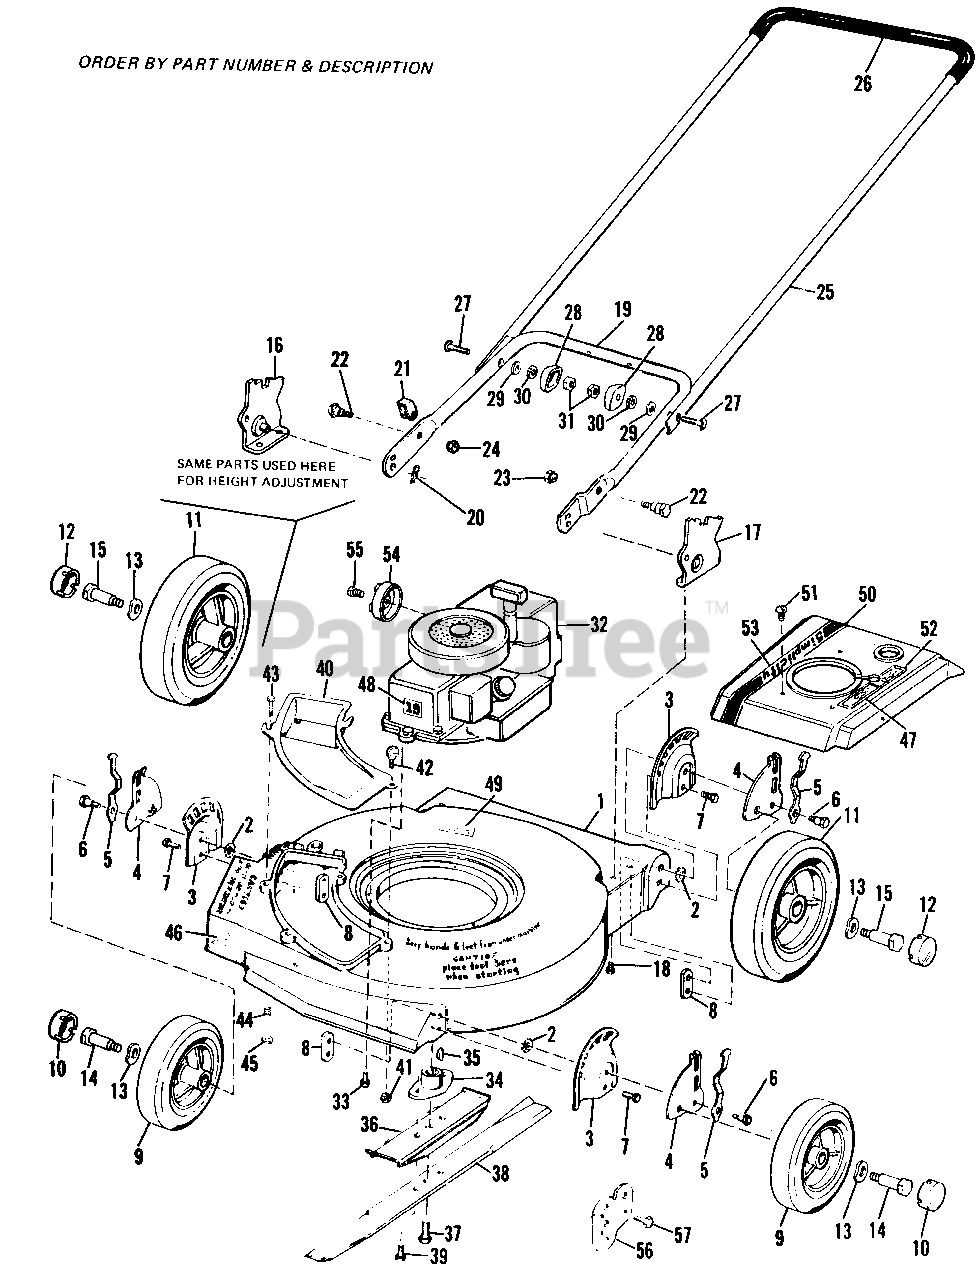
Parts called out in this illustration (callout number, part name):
1	HOUSING, 19"
2	LOCKWASHER, Shake Proof, 3/8" Ext. Type
3	PLATE, Adjusting
4	ADJUSTER, Height, Front & Rear
5	SPRING, Height Adj.
6	BOLT, Shoulder, Hex Hd.
7	CAPSCREW, Hex, 3/8-16 x 5/8
8	NUT, Pilot Twin
9	WHEEL & TIRE ASSY, 6" (Front)
10	CAP, Hub, 6"
11	WHEEL & TIRE ASSY, 8" (Rear)
12	CAP, Hub, 8"
13	WASHER, Spring
14	BOLT, Wheel, Front
15	BOLT, Wheel, Rear
16	BRACKET ASSY, R.H.
16	BRACKET ASSY, L.H.
17	BRACKET ASSY, R.H.
17	BRACKET ASSY, L.H.
18	SCREW, Thd Forming, 1/4-20 x 3/8
19	HANDLE, Lower
20	CLIP, Hair Pin
21	LATCH, Handle
22	BOLT, Latch, Handle
23	NUT, Latch, Handle
24	SCREW, Hex Hd., Self Tap., 1-1/2
25	HANDLE, Upper (990666 only)
25	HANDLE, Upper
26	TUBING, Handle
27	BOLT, Curved Hd.
28	NUT, Wing
29	WASHER, Plain, 1/4
30	BAFFLE, Muffler
31	NUT, Hex, Full Lock, 5/16-18
32	ENGINE, Briggs & Stratton
33	SCREW, Thd. Forming, 3/8-16 x 1
34	ADAPTOR, Blade
35	KEY, Woodruff, 5/32 x 5/8
36	STIFFENER, Blade
37	CAPSCREW, Hex,3/8 x 1-1/2 Gr.8
38	BLADE, 19"
39	BOLT, 5/16-18 x 1
40	PLATE, Cover
41	NUT, Speed, Special
42	SCREW, Thumb, 1/4 x 5/8
45	NUT, Full Lock, 1/4-20
46	DECAL, Safety Std.
47	FILM, Instruction
48	FILM, Numeral, Engine
49	PLATE, Serial No.
51	SCREW, Rd. Hd., #8 x 1/2 Phillips
52	FILM, Throttle Control
53	FILM, Simplicity
54	PIVOT ASSY
55	WASHER
56	BOLT, Shoulder, Hex Hd.
57	NUT, Hex, Full Lock, 3/8-16
58	WASHER
59	SPACER
60	ADJUSTER, Height
61	GUARD ASSY, Stone
62	CAPSCREW, Hex Hd., 1/4-20 x 1/2
63	LOCKWASHER, 1/4
64	LOCKWASHER, Full, 5/16
65	BRACKET, Wheel (990678 Only)
66	CAPSCREW, Hex, 3/8-16 x 5/8 (990678 Only)
